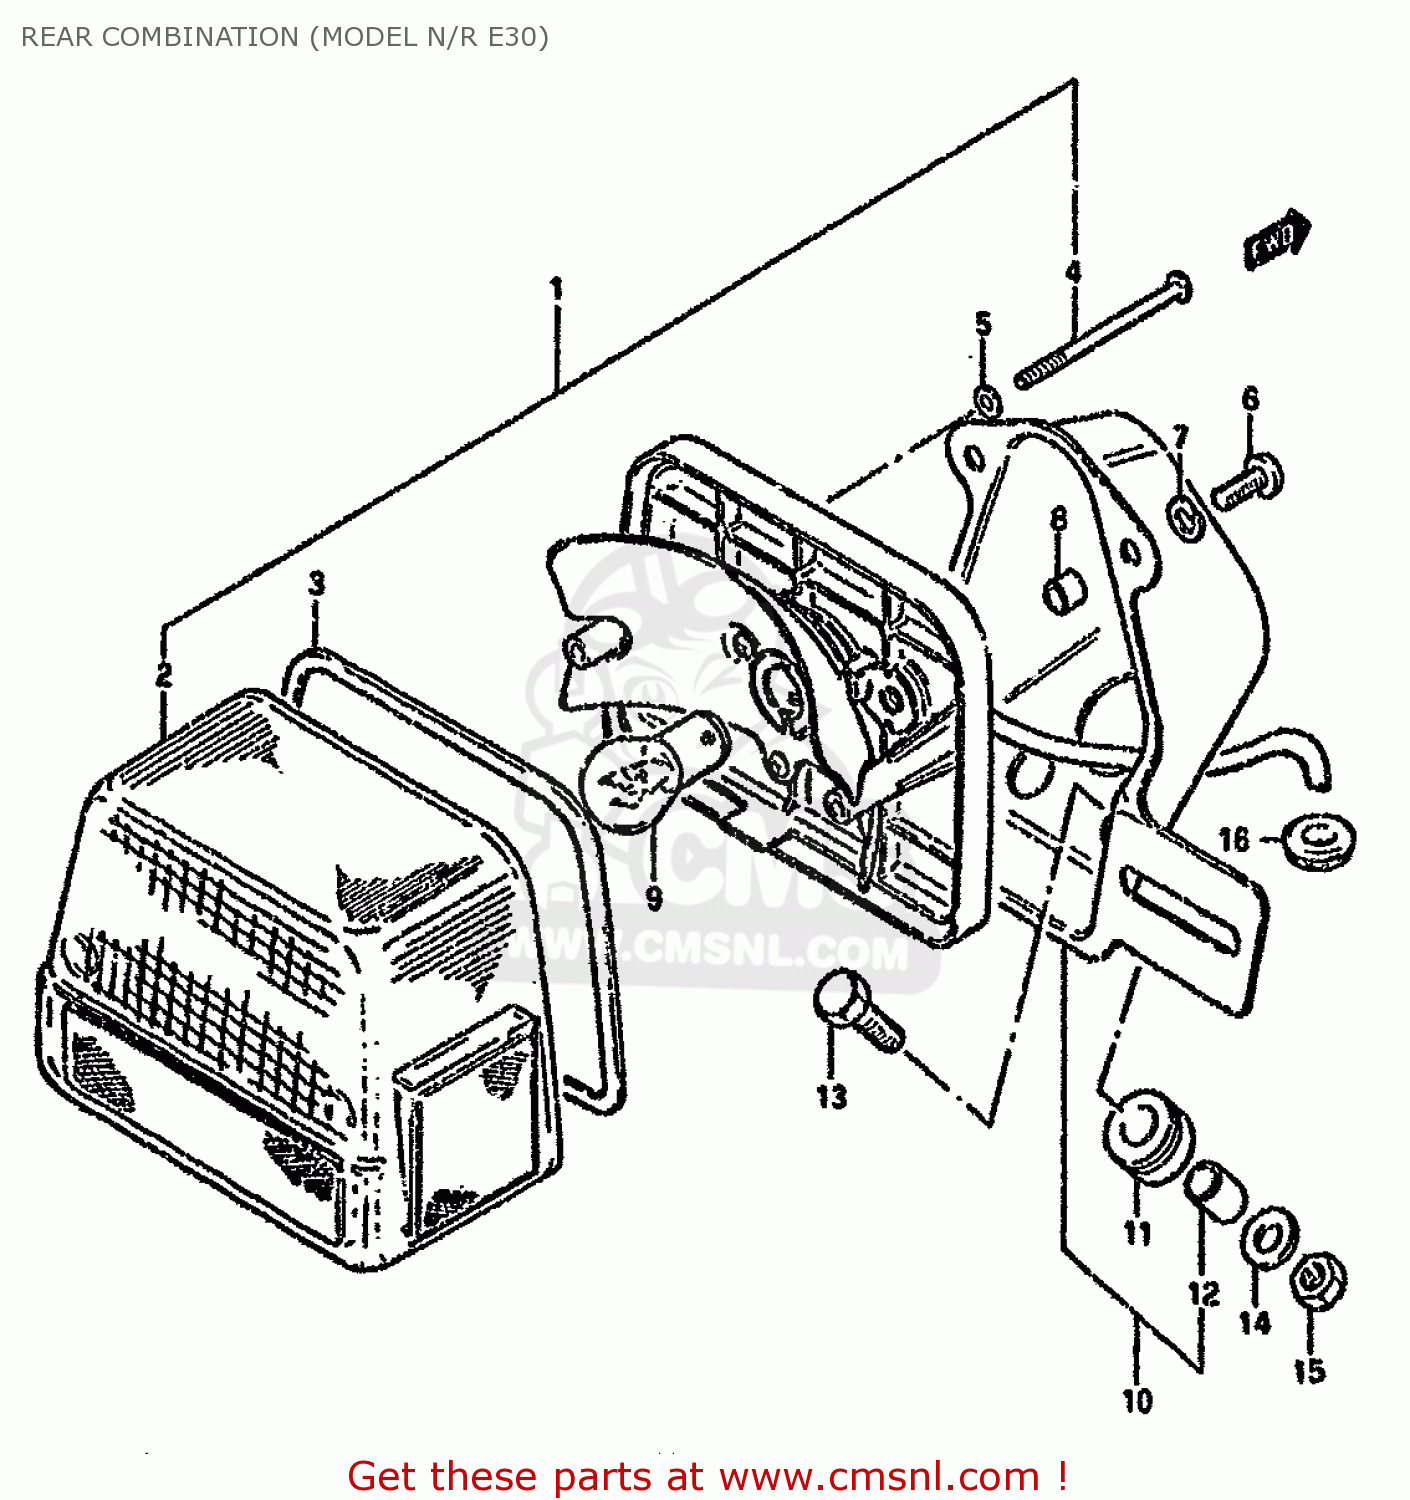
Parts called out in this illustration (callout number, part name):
1	LAMP UNIT,REAR COMBINATION
2	LENS
3	GASKET (NAS)
4	SCREW
5	GASKET (NAS)
6	SCREW
7	LOCK WASHER
8	SPACER
9	BULB(12V23W)
10	BRACKET UNIT,TAIL LAMP
11	CUSHION
12	SPACER
13	BOLT(6X25)
14	BOLT
15	NUT
16	WASHER
17	NUT 6MM
18	GROMMET
